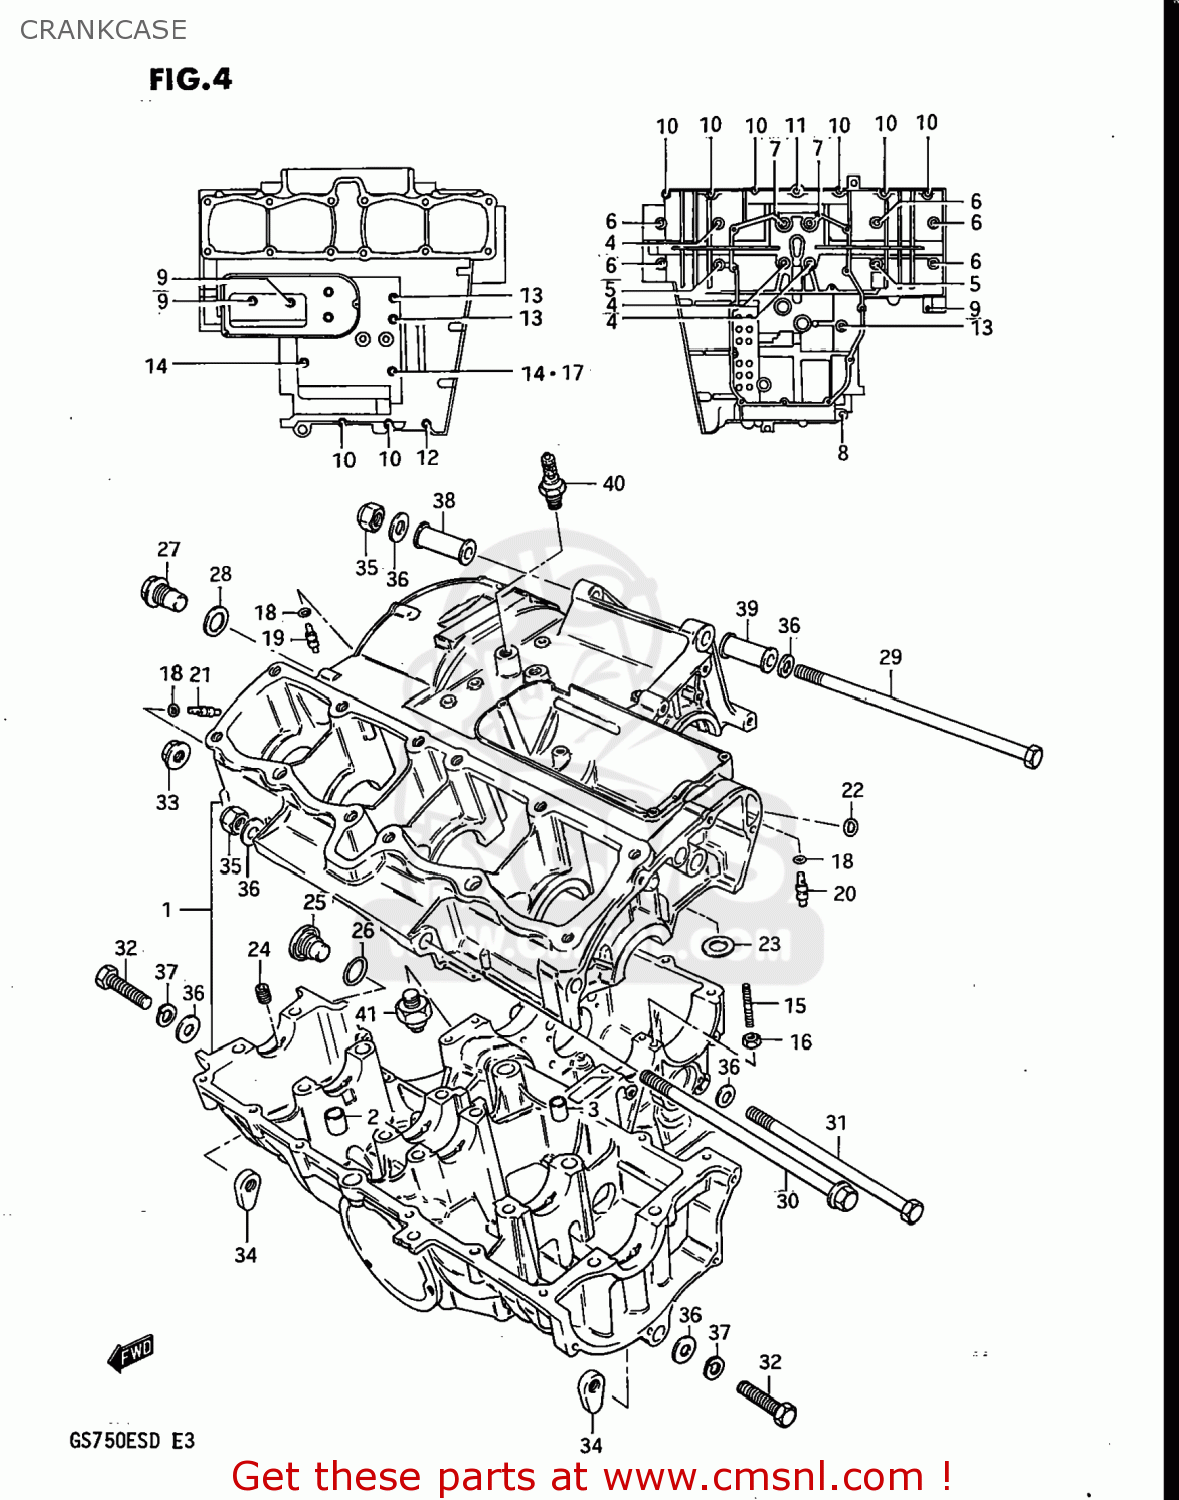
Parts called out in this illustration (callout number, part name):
1	CRANKCASE SET
2	PIN(10.4X13X22)
3	PIN (11X20)(SUS)
4	BOLT
5	BOLT(8X135)
6	BOLT
7	BOLT
8	BOLT 8X60
9	BOLT
10	BOLT (6X40)
11	BOLT 6X50
12	BOLT 6X55
13	BOLT
14	BOLT (5X95)
15	STUD BOLT (6X45)
16	NUT
17	GASKET(6.2X13X1.2) (NAS)
18	O RING(D:1.2,ID:4)
19	JET,OIL GALLERY
20	JET(8)
21	JET,OIL
22	O RING(D:3.2,ID:12.9)
23	WASHER,THRUST
24	JET,AIR
25	PLUG
26	O RING(D:2.4,ID:16.8)
27	PLUG
28	GASKET(14X19.2X2) (NAS)
29	BOLT 10X255
30	BOLT
31	BOLT
32	BOLT
33	NUT 10MM
34	NUT
35	NUT
36	WASHER
37	LOCK WASHER
38	SPACER,ENGINE MOUNT
39	SPACER,ENGINE MOUNT(L:50)
40	GAUGE ASSEMBLY,OIL TEMPERATURE
41	SWITCH ASSEMBLY
